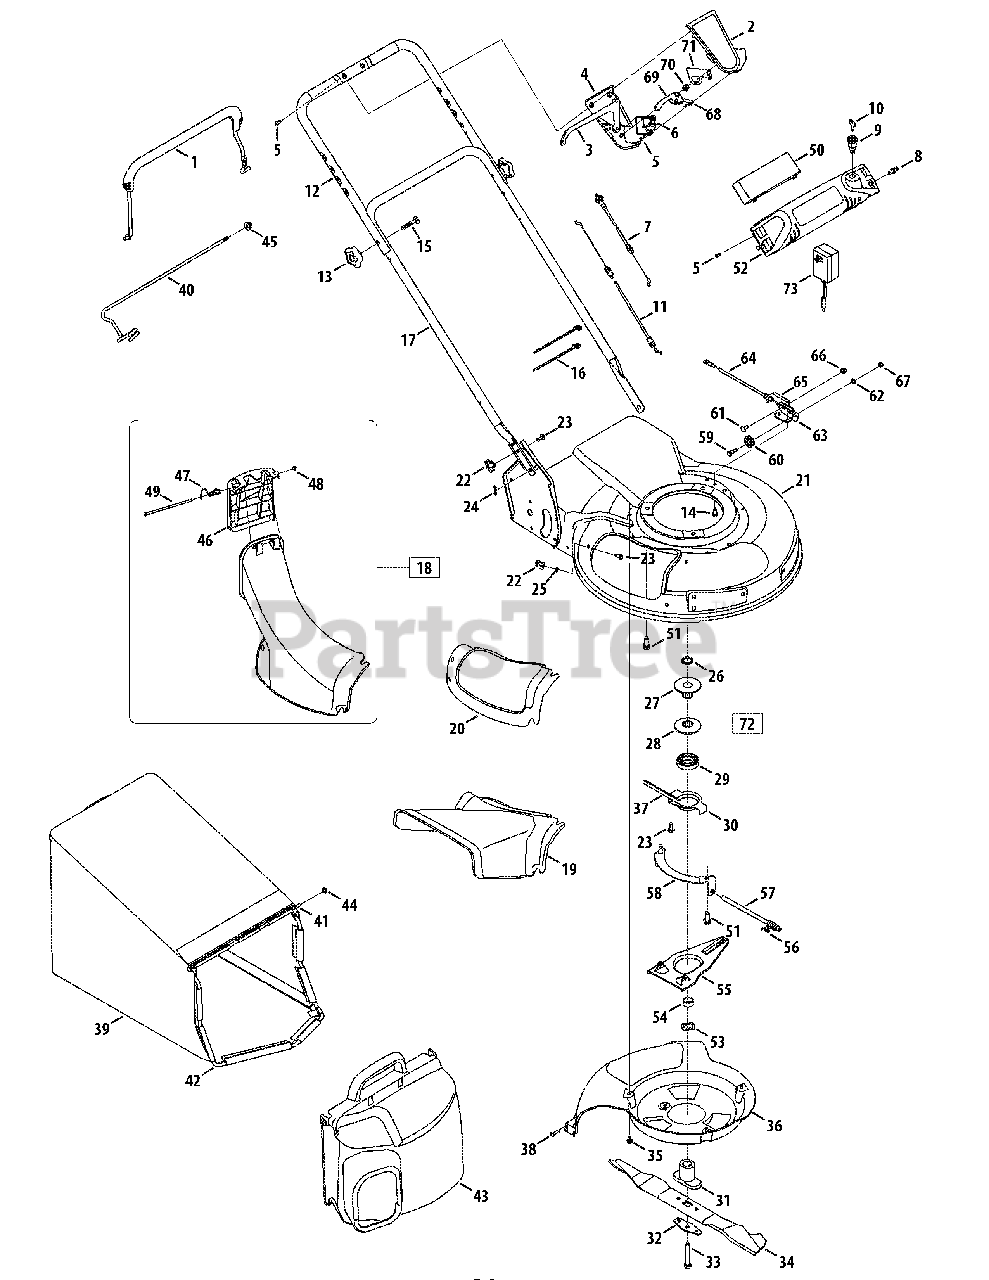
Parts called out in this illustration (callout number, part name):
1	Blade Control
2	Upper Control Housing
3	Drive Control
4	Lower Control Housing
5	C Sunk Tap Screw, #10 x.75 Lg
6	Cable Mounting Cap
7	Drive Cable
8	Rivet
9	Key Switch
11	Control Cable
12	Upper Handle
13	Star Knob
14	Screw, 1/4-20 x .625
15	Carriage Bolt, 5/16-18 x 2.0
16	Cable Tie
18	Adapter Assembly
19	Side Discharge Chute
20	Mulch Cover
22	Wing Nut
23	Carriage Bolt, 1/4-20 x .75"
24	Cotter Pin
25	Push Nut, .25 x ID x .50 OD
26	Sleeve Spacer, .88ID x 1.13OD
27	Half Pulley: 2.62 OD
28	Half Pulley: 2.62 OD x 1.61
29	Ball Bearing
31	Blade Adapter
32	Blade Bell Support
33	Hex Bolt, 3/8-24 x 2.5
34	21" Mulching Blade
35	Screw, 1/4-20 x 3.75
36	Baffle
37	Belt, 3/8 x 39.24
38	Screw, 1/4-15 x .750
39	Grass Catcher
40	Support Rod w/ Rope Guide
41	Pivot Rod
42	Grass Catcher Frame
43	Grass Catcher Cover
44	Cap Nut
45	Flange Lock Nut, 5/16-18
46	Chute Door
47	Torsion Spring
48	Push Cap
49	Pivot Rod
50	12V Battery
51	Sems Screw, 3/8-16 x 1.00
52	Harness Assembly
53	Wave Washer, 1.38 ID x.88 OD
54	Slve Spacer, .88 ID x 1.00 OD
57	Pivot Shaft
59	Shlder Screw, .375 ID x 1/4-14
60	Cable Roller
61	Carriage Screw, 1/4-20 x .62
62	Lock Washer, 1/4
63	Cable Mounting Bracket
64	6 Speed Cable
65	Cable Adjustment Bracket
66	Hex Nut 1/4-20
67	Hex Nut 1/4-28
68	Shift Lever Spring
69	6 Speed Shift Lever
70	Gear Insert
71	6 Spd. Rack Cable Bracket
72	Pulley Assembly
73	12V Battery Charger
